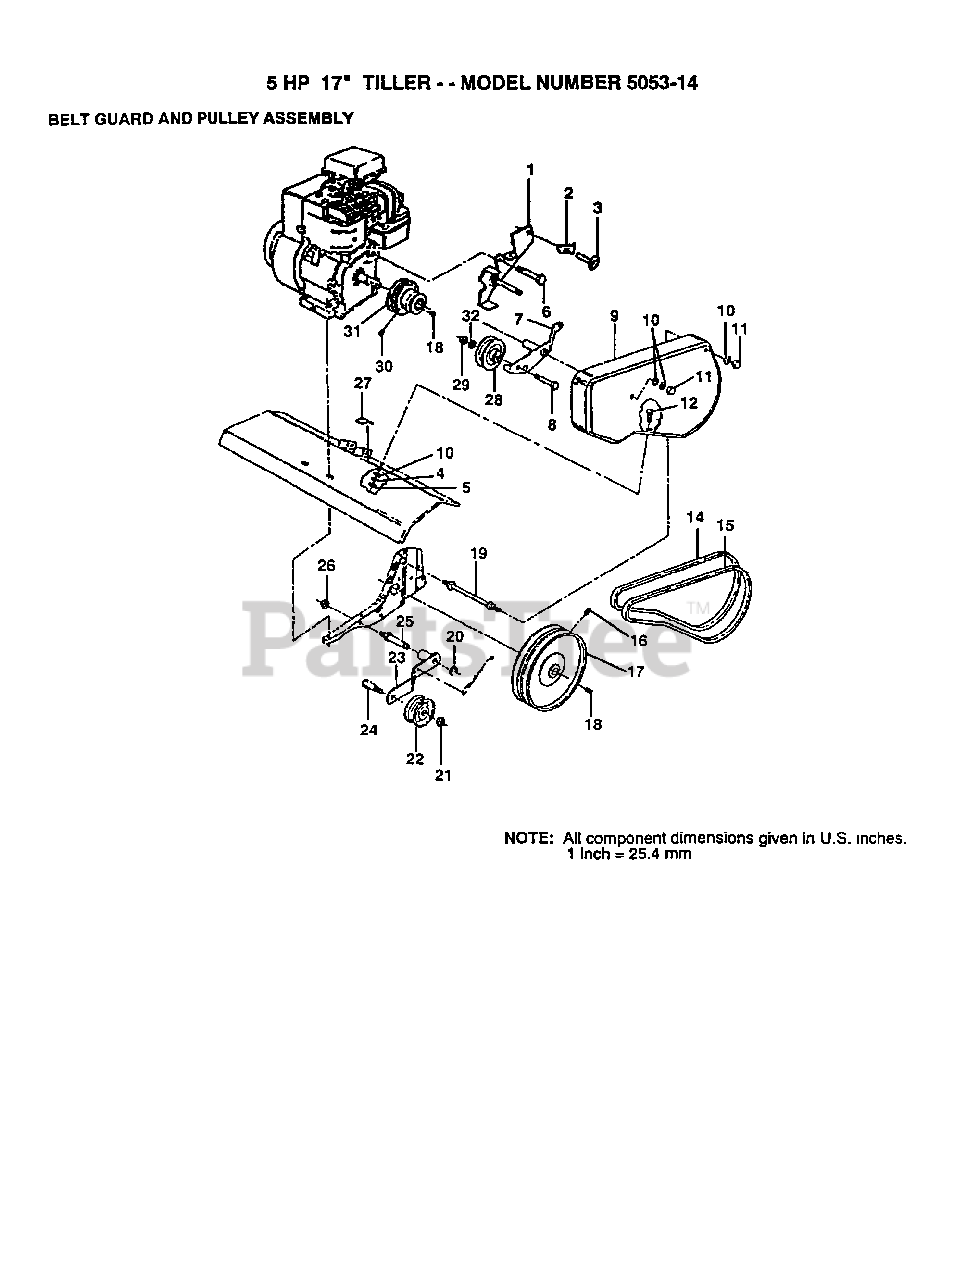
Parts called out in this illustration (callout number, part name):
2	CONDIUT CLIP T
4	LOCKWASHER
10	WASHER
11	NUT-CAP TI
12	BOLT T
18	KEY T
19	BOLT TI
20	KLIP RING TI
21	NUT
23	IDLER ARM TI
25	SHAFT IDLER TI
26	JAM NUT TI
27	PAD IDLER TI
28	PULLEY W/SPACER
29	NUT.HEX.3/8-16UNC
30	SET SCREW
31	ENGINE PULLEY TI
32	WASHER
